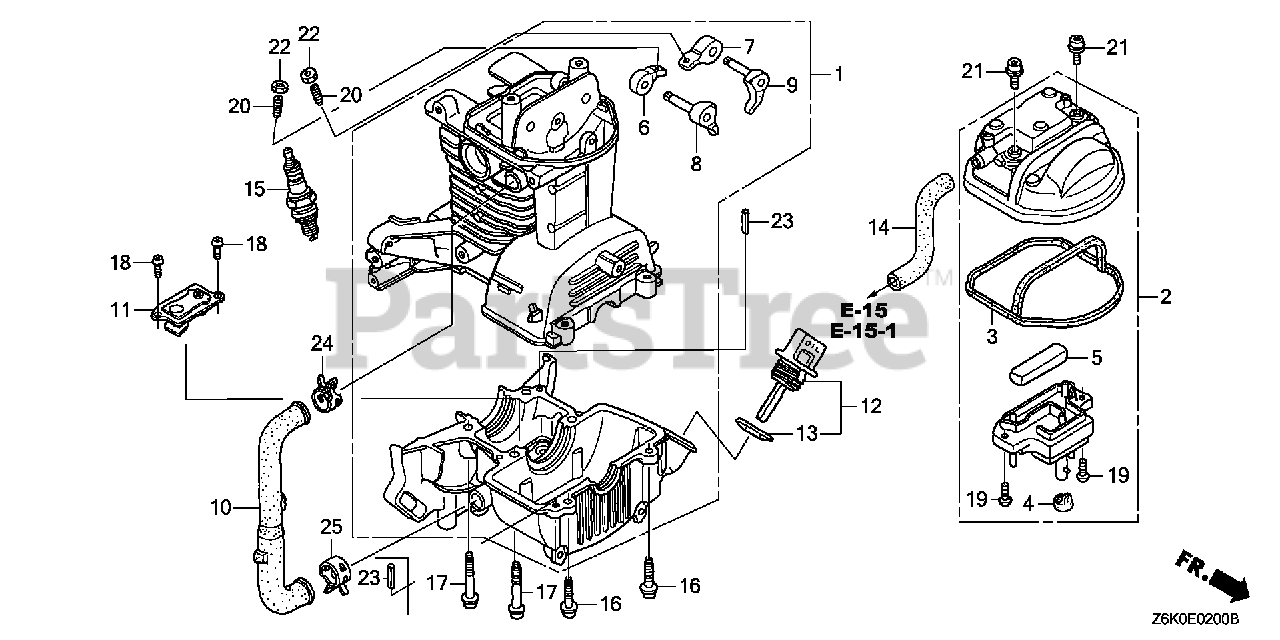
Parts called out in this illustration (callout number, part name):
1	CRANKCASE SET
2	COVER, CYLINDER HEAD
3	SEAL, HEAD COVER
4	GROMMET, HEAD COVER
5	FILTER, BREATHER
6	ARM, IN. VALVE ROCKER
7	ARM, EX. VALVE ROCKER
8	LIFTER, IN. VALVE
9	LIFTER, EX. VALVE
11	PLATE ASSY., OIL OUTLET VALVE
12	CAP ASSY., OIL FILLER
13	GASKET, OIL FILLER CAP
14	TUBE, BREATHER
15	SPARK PLUG (CMR4H) (NGK)
15	SPARK PLUG (CMR5H) (NGK)
15	SPARK PLUG (CMR6H) (NGK)
16	BOLT, SOCKET (5X20)
17	BOLT, SOCKET (5X32)
18	SCREW, PAN (4X8)
19	SCREW, PAN (4X8)
20	SCREW, TAPPET ADJUSTING
21	BOLT, SOCKET (5X12)
22	NUT, TAPPET ADJUSTING
23	PIN, SPRING (4X10)
24	CLAMP, TUBE (D12)
25	CLAMP, TUBE (D13)
